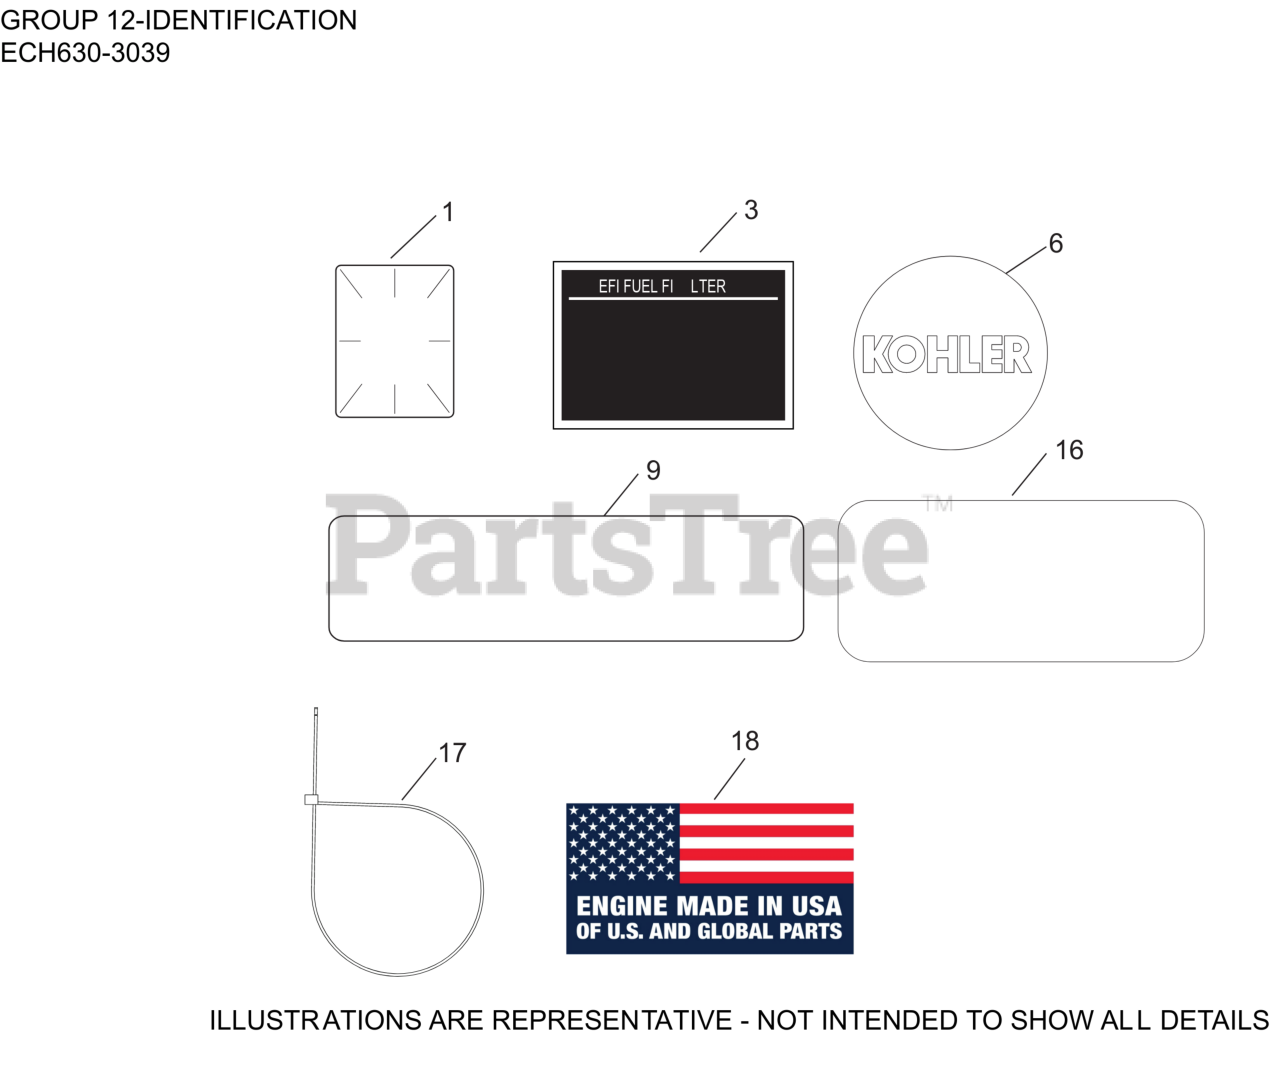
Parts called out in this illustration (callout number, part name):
1	LABEL, CLEAR LAMINATION
3	LABEL, EFI FUEL FILTER
6	LABEL, GRASS SCREEN
9	DECAL LPAC, 21 HP/694cc/ECV-ECH650
16	LABEL, CANADIAN COMPLIANCE
18	DECAL, USA
